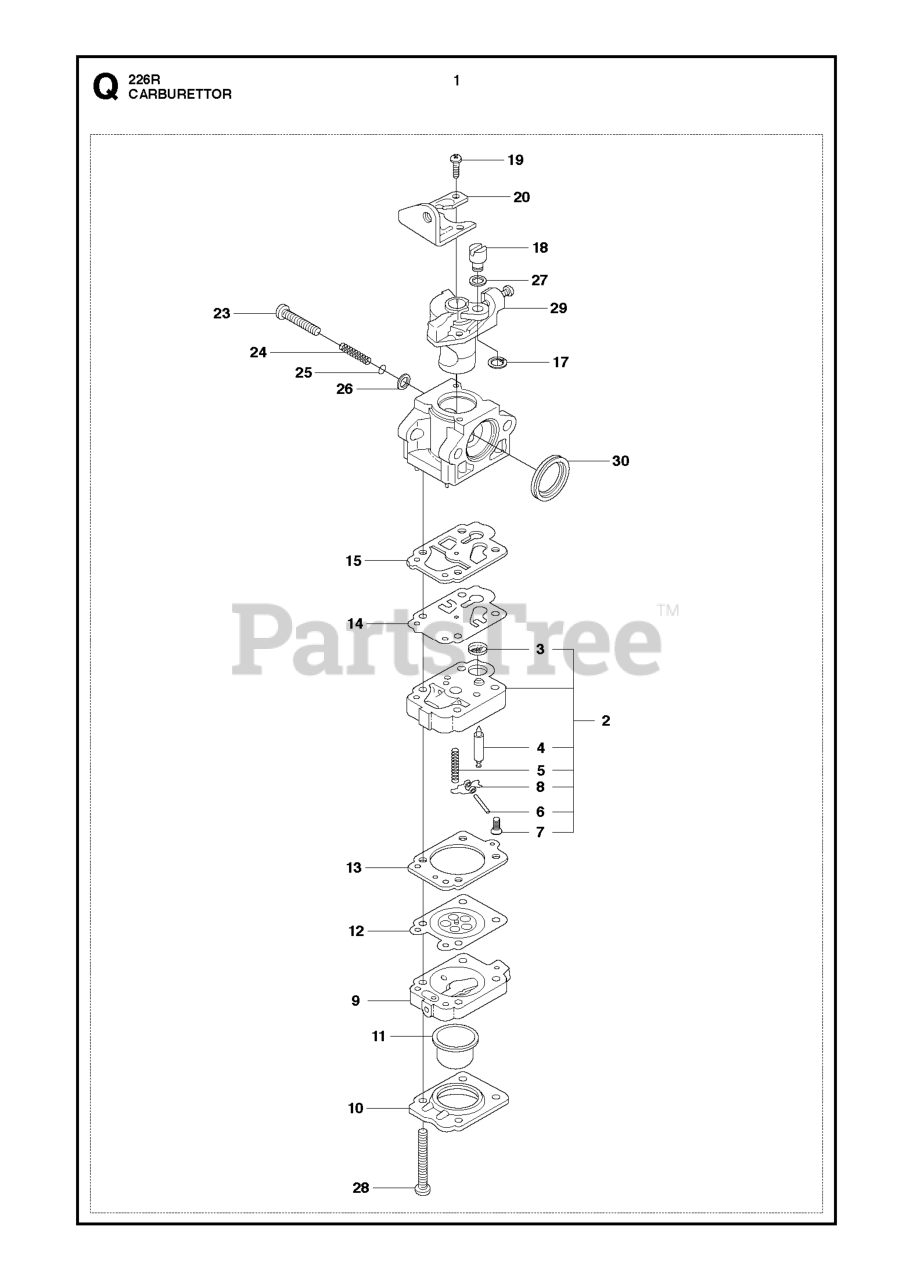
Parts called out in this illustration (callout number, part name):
1	CARBURETOR-A
3	SCREEN
4	VALVE INLET
24	SPRING
30	RING PACKING
